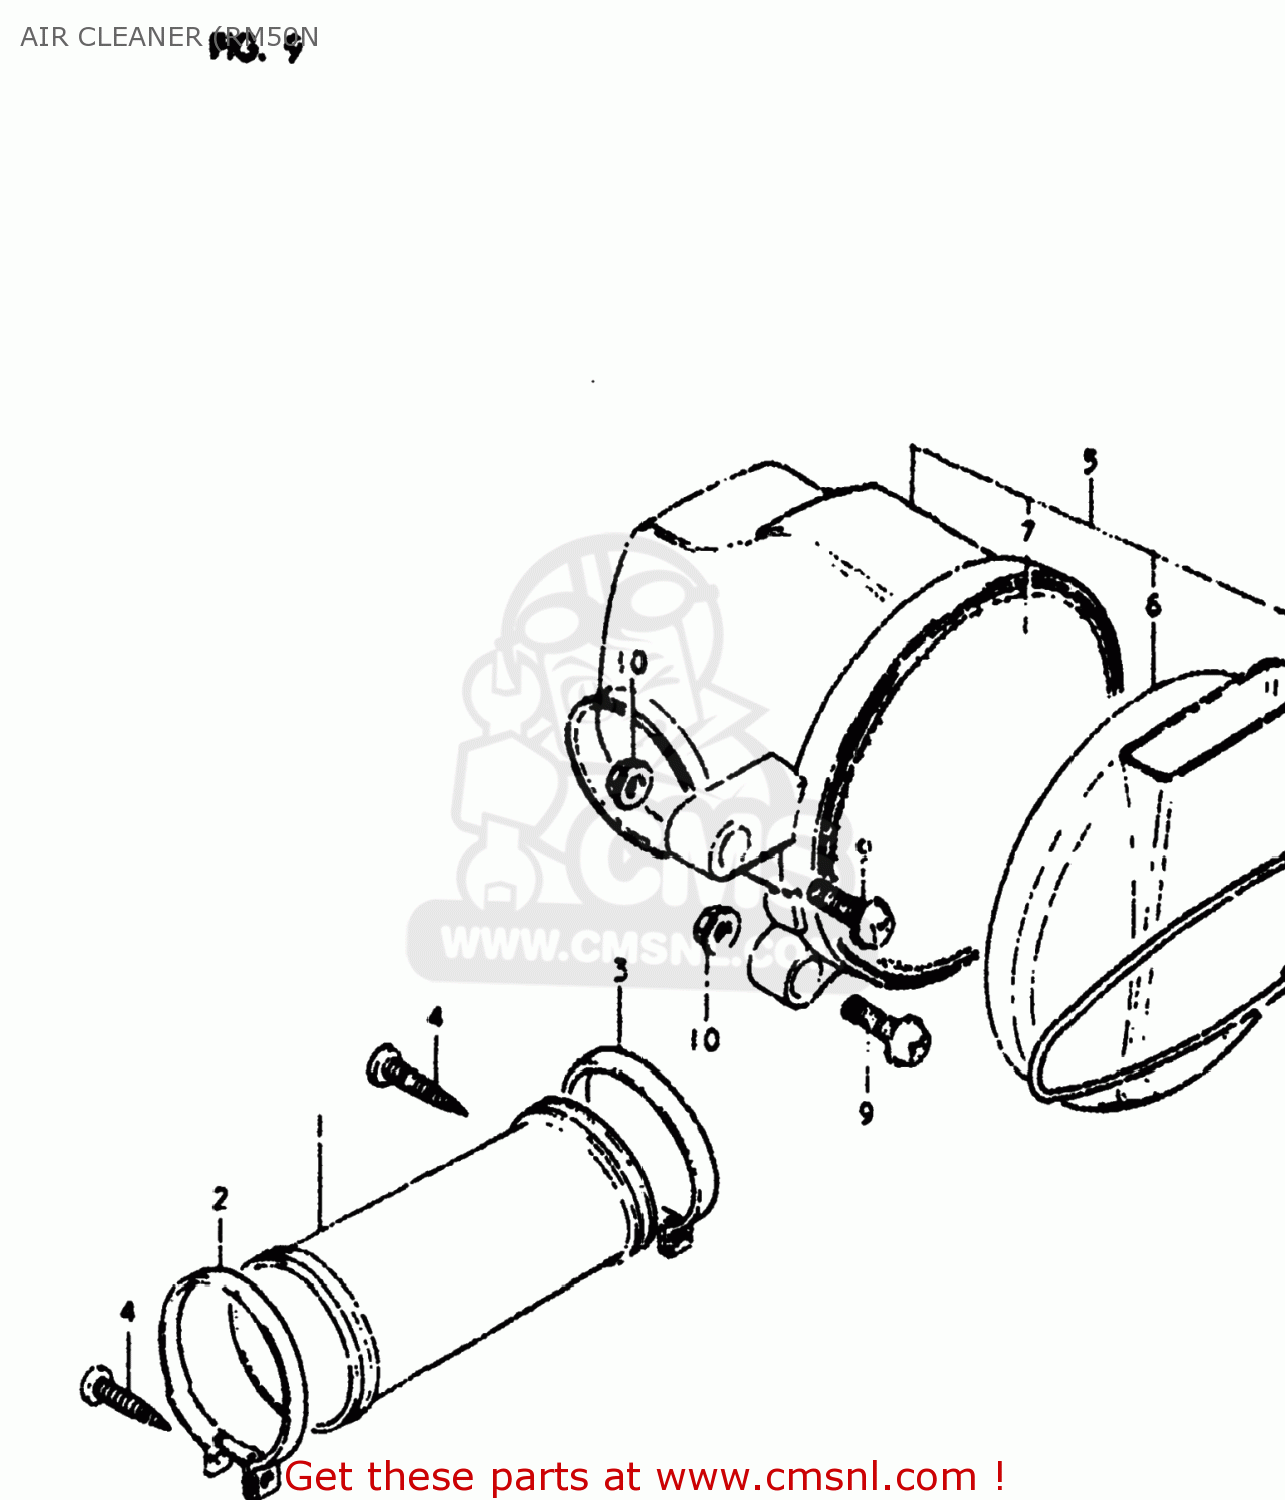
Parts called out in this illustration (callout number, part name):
1	HOSE,CARBURETOR AIR INLET
2	CLAMP
3	CLAMP
4	SCREW TAPP.
5	CLEANER ASSEMBLY,AIR
6	CAP
7	FILTER
8	O-RING,AIR CLEANER
9	SCREW
10	NUT
